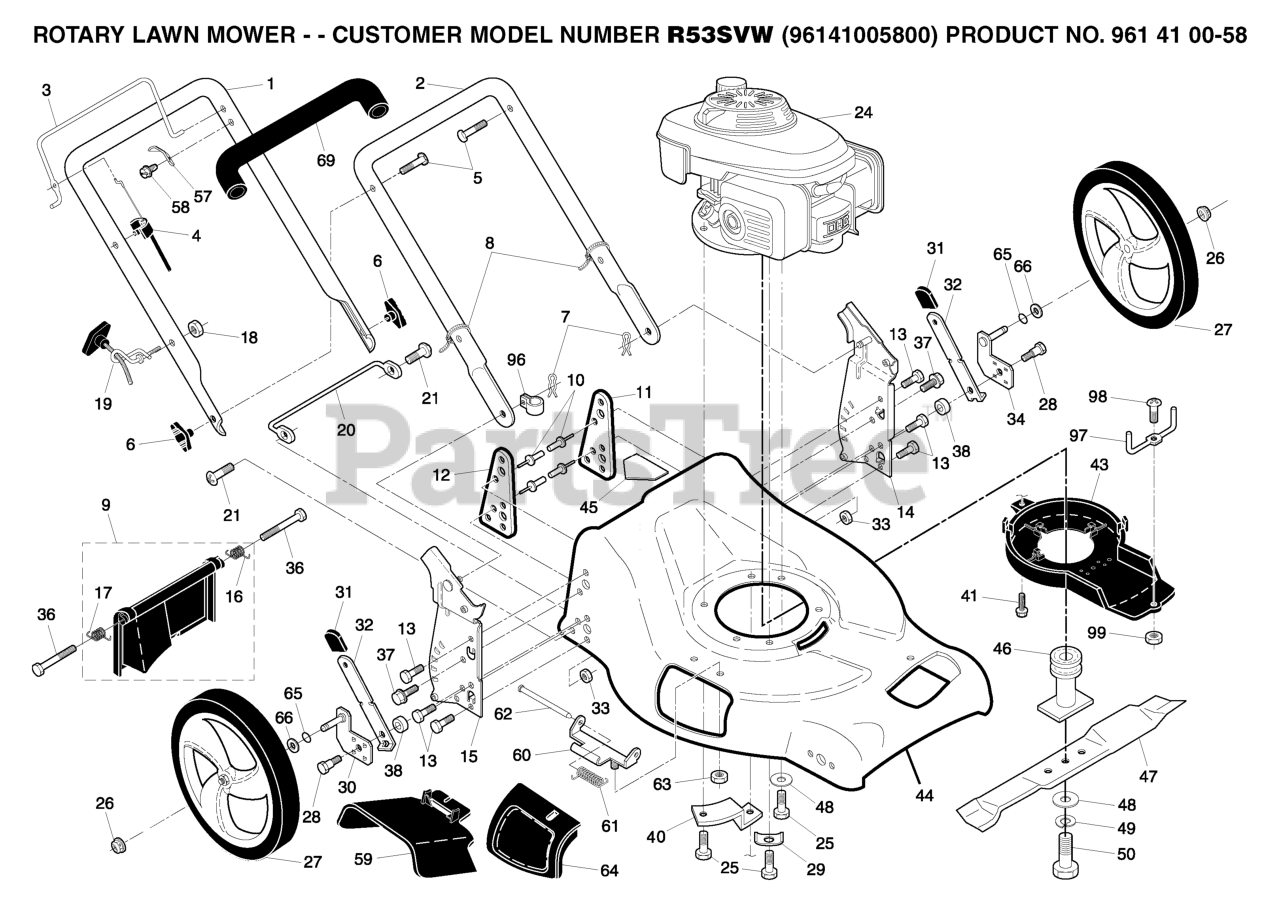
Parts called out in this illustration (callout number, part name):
1	RP HANDLE.ASM.UPPER.W/GRI
2	LOWER HANDLE
3	BAIL.DSTRT.FL.AW.CREAS.ORANGE
4	CABLE.ENGINE BRAKE.MZR
5	BOLT, HANDLE 5/16-18X1.75
6	KNOB, DEFLECTOR
7	HAIRPIN COTTER
8	TIE GUIDE
9	KIT.DOOR.RR.ASM.21.FWGD
10	RIVET BLIND
11	SUPPORT BRACKET LH
12	SUPPORT BRACKET RH
13	SCREW 14-20 X 5/8
14	BRKT.ASM.HNDL.21FGD.EZ
15	BRKT.ASM.HNDL.21FGD
17	SPRING.REAR.DOOR.EZ.21
18	NUT
19	RB GUIDE.ROPE.STD.BLK.ZIN WSL
25	BOLT 3/8-16X1-1/8
26	NUT
28	SHOULDER BOLT
29	WASHER.ENGINE.BZP
30	ARM.ASM.AXLE.H/W,RR.BZ
31	SELECTOR KNOB
32	SPRING.SELECTOR.21.FWG.ZINC
33	NUT.71038.31-18.HEX.NYLOCK
34	ARM.ASM.AXLE.H/W.LR.BZ
37	SELF-TAPPING SCREW 5/16-18X3/4
38	WASHER.FLAT.34X1.38X22
40	BRACKET
41	SCREW.HEX.WSH
43	DEBRIS SHIELD
45	DECAL.INTERNATIONL.CUTFINGER
46	Blade Adapter / Pulley
47	BLADE.21.PUSH
48	WASHER,HARDEN
49	LOCKWASHER
50	SCREW, HEX HD 3/8-24 X 1-3/8
57	BRACKET UPSTOP
59	DEFLECTOR.CLIPPIN.21.FGD
60	BRACKET.ASM.HINGE.21.FWGD.
61	SPRING.TORSION
62	ROD.HINGE.21
63	LOCKNUT.NYLOC.1/4-20
64	DOOR.MULCH.21.REAR.FWGD
65	O-RING..070X.487.NEOPRENE
66	WASHER.FLAT.1/2
69	GRIP.HANDLE.FOAM.WIDE.(1 SIDE)
96	CLIP.CABLE.BLK
97	KEEPER.BELT.FGD
98	SCREW.#8.MACH
99	NUT.HEX.#8
